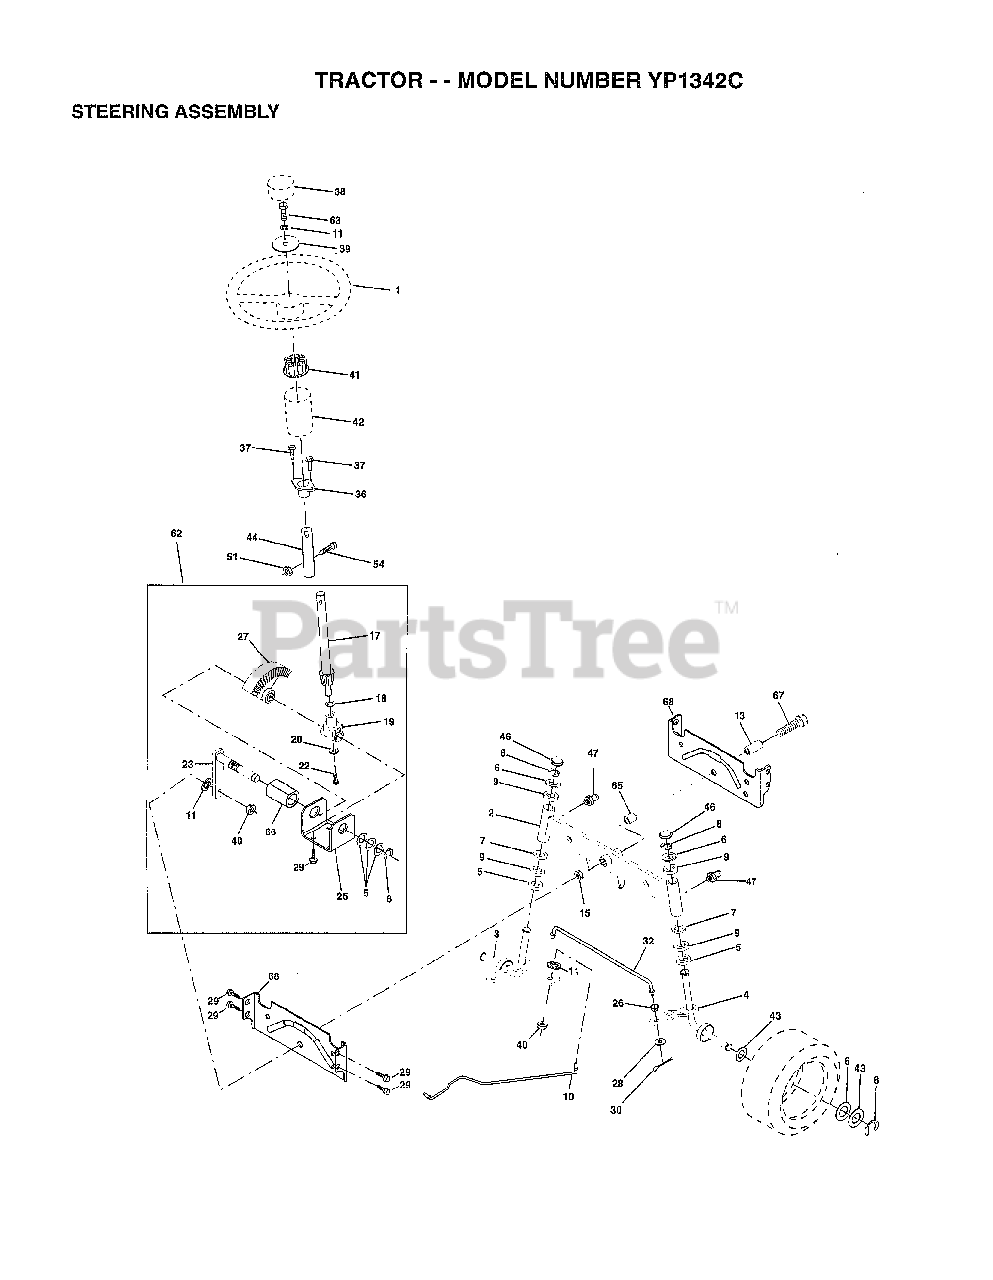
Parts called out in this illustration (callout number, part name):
1	WHEEL STR AYP BLK
2	AXLE ASM
3	SPINDLE.ASM.LH
4	"SPINDLE ASM,RH"
5	WASHER .T
6	WASHER
7	WASHER
8	RING
9	COL. SRTG. BEAR.
10	DRAGLINK-STAMPED
11	LOCKWASHER
13	BEARING AXLE
15	"NUT-LOC,FLANGE LT"
17	SHAFT ASM STEERIN
18	THRUST WASHER
19	SUPPORT.SHAFT
22	SCREW HEX SOC1/4-
25	BRKT-STEERING
26	BUSHING.DRAGLINK
27	GEAR SECTOR
28	WASHER
29	SCREW
30	COTTER PIN
32	TIE ROD
36	BUSHING.STEERING
37	"SCREW-TT,10-32 FL"
38	CAP STEER AYP
39	WASHER T
40	GRIPCO NUT
41	ADAPTER LT
42	BOOT.STEER.PL
44	EXT SHAFT STEERIN
46	CAP
47	ZERK M
51	NUT
54	BOLT
62	KIT STEERING ASM
63	BOLT
65	SPACER AXLE
66	"BEARING-ARM,PITMA"
67	BOLT
68	BRACE AXLE
